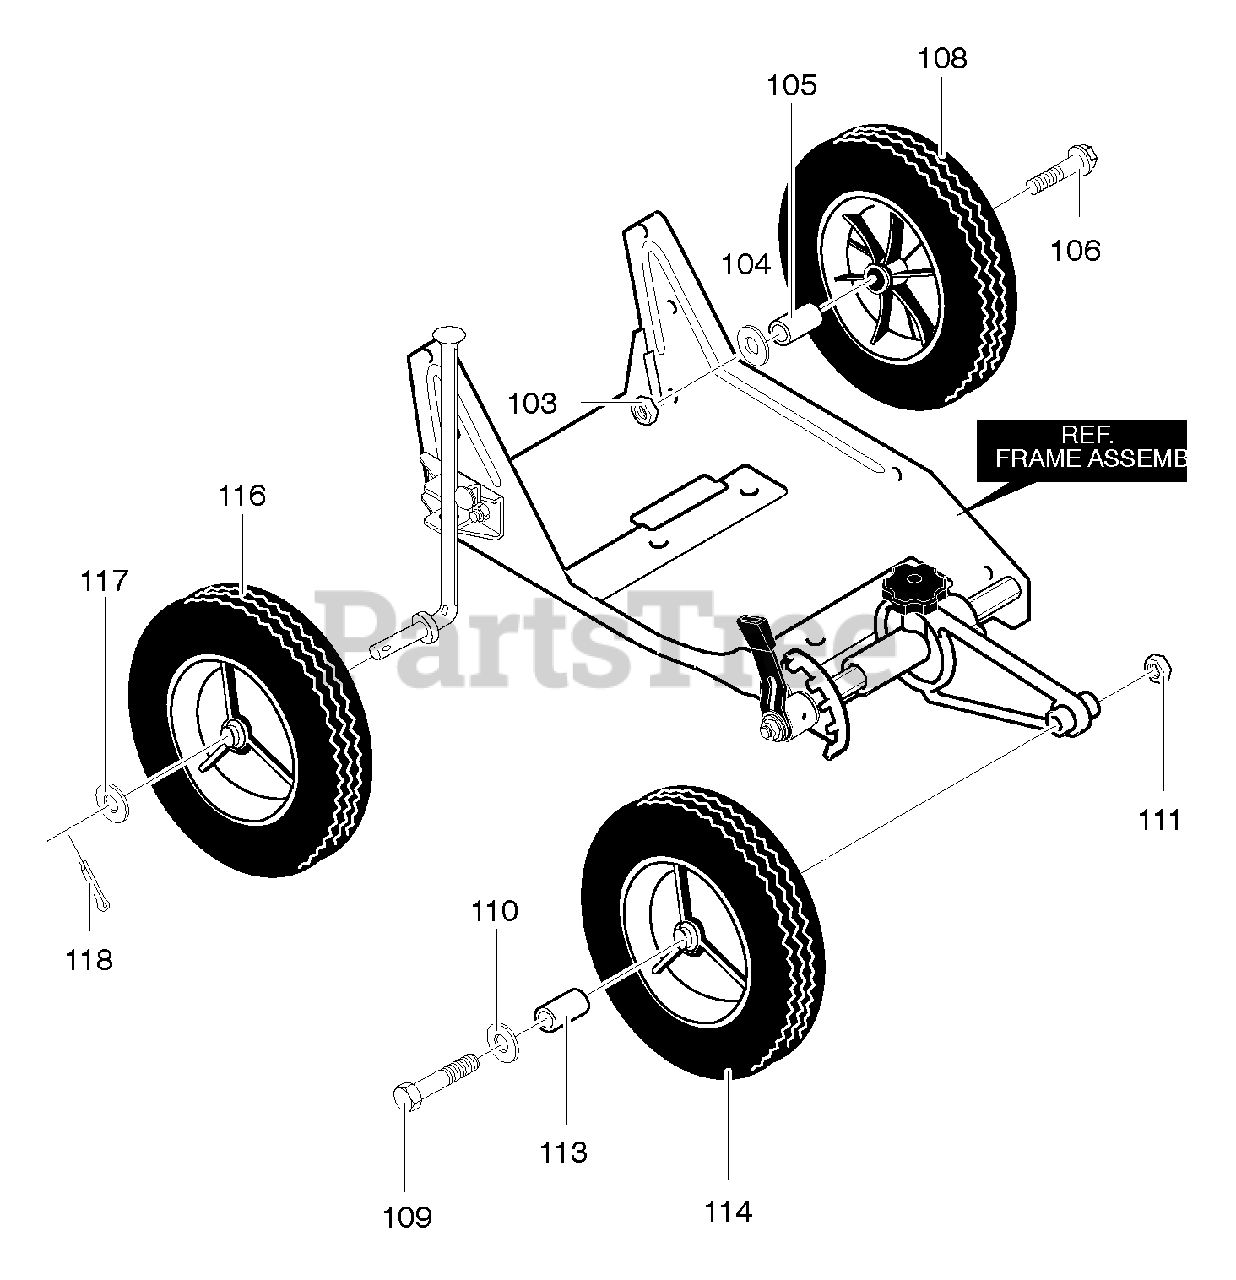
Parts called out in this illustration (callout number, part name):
103	Nut, 3/8-16
104	Washer
105	Spacer, Sleeve
106	Bolt, HHSH 3/8
108	Tire & Rim
109	Screw, 5/16-18 x 3.00
110	Flatwasher
111	Nut, 5/16-18
113	Spacer, Sleeve
114	Tire & Rim
116	Tire & Rim
117	Flatwasher
118	Cotter Pin
